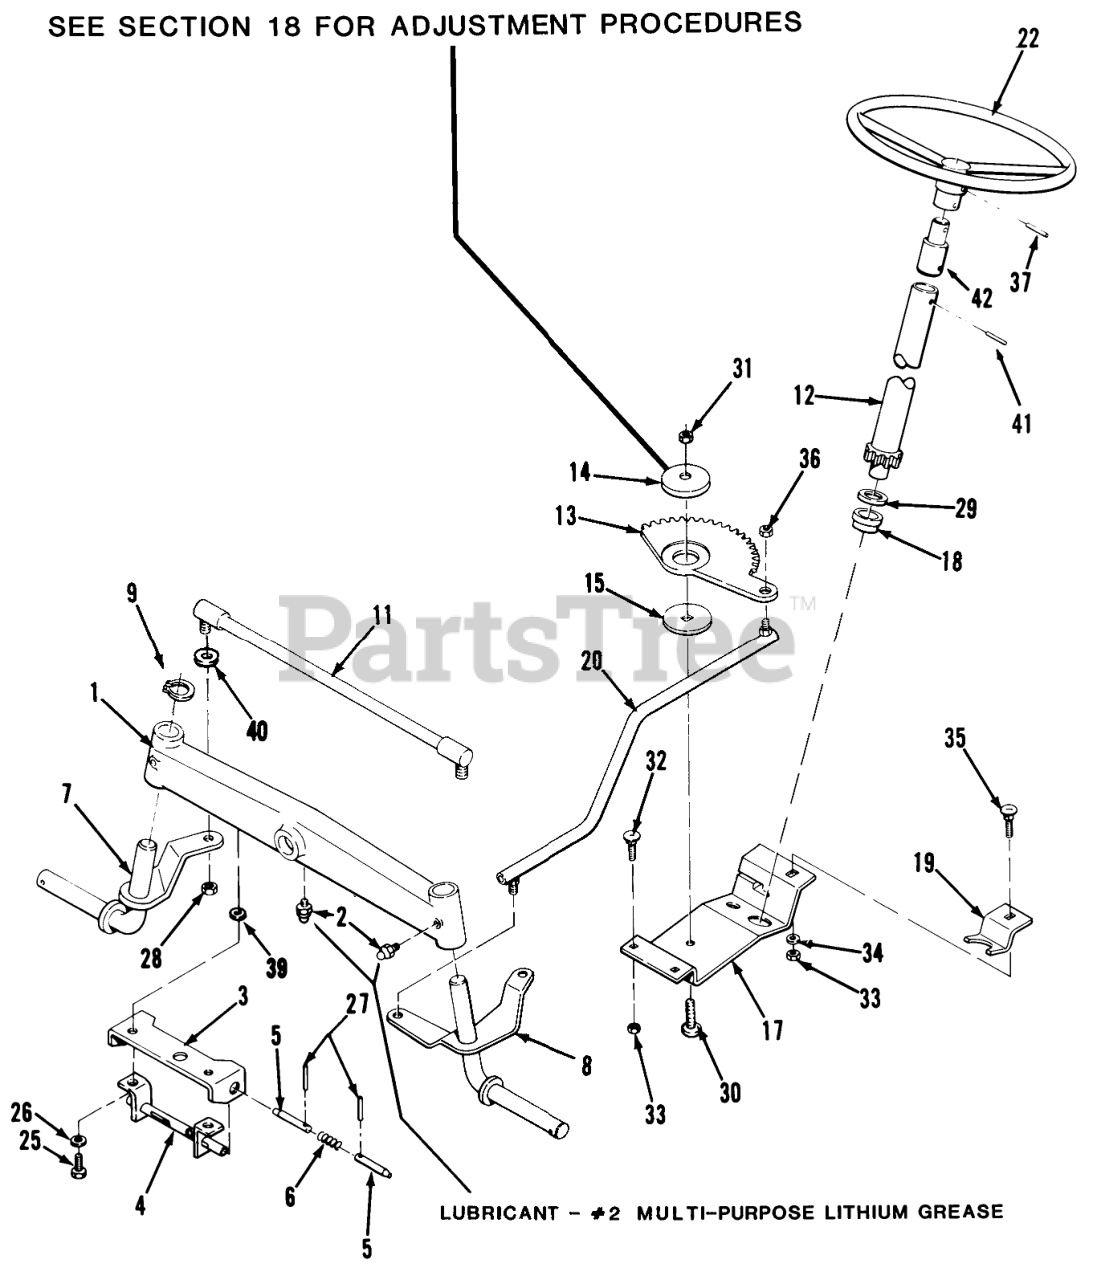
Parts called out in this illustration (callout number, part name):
8	FRONT SPINDLE ASSY LH *R
14	BUSHING
15	WASHER-BEARING
18	BEARING-WHEEL
27	SPIROL PIN
29	SHIM-WASHER
31	NUT-HEX
34	WASHER 5/16 SAE
37	SPIROL PIN 5/16X13/8
39	WASHER
40	WASHER-SPECIAL
42	SHAFT COUPLER
